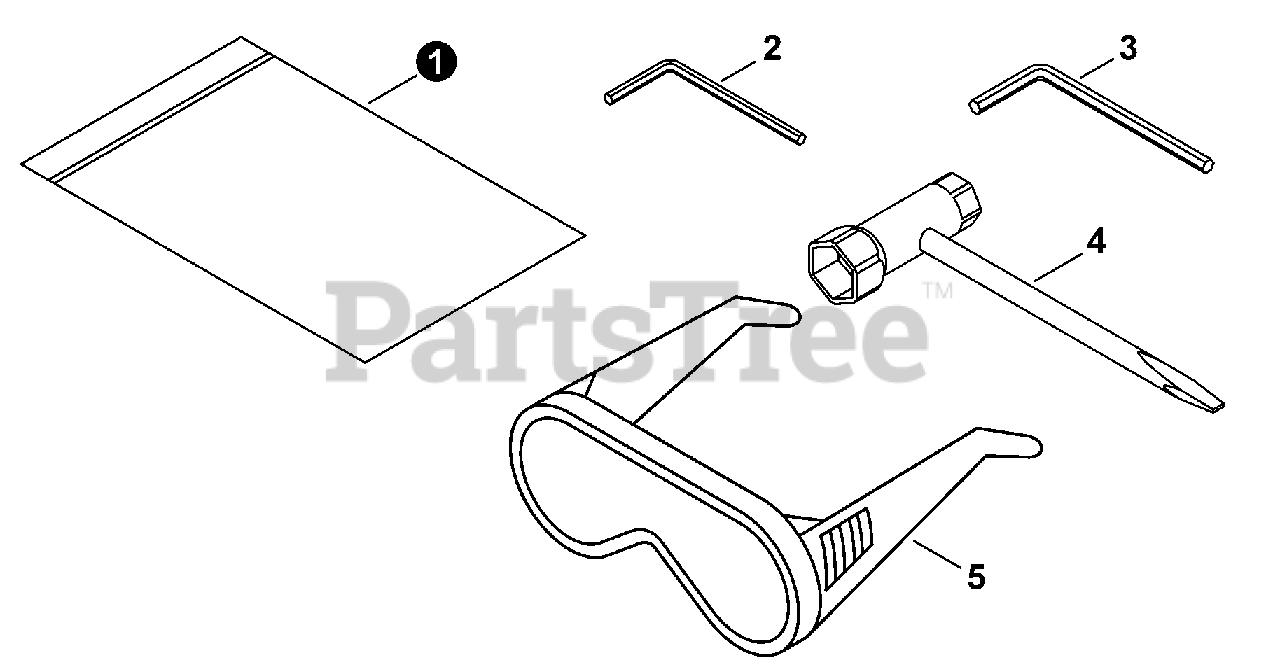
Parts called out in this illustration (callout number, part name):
1	BAG, TOOL
2	WRENCH, ALLEN 4 MM
3	WRENCH, ALLEN 5 MM
4	T-WRENCH 17×19 MM
5	GLASSES, SAFETY
